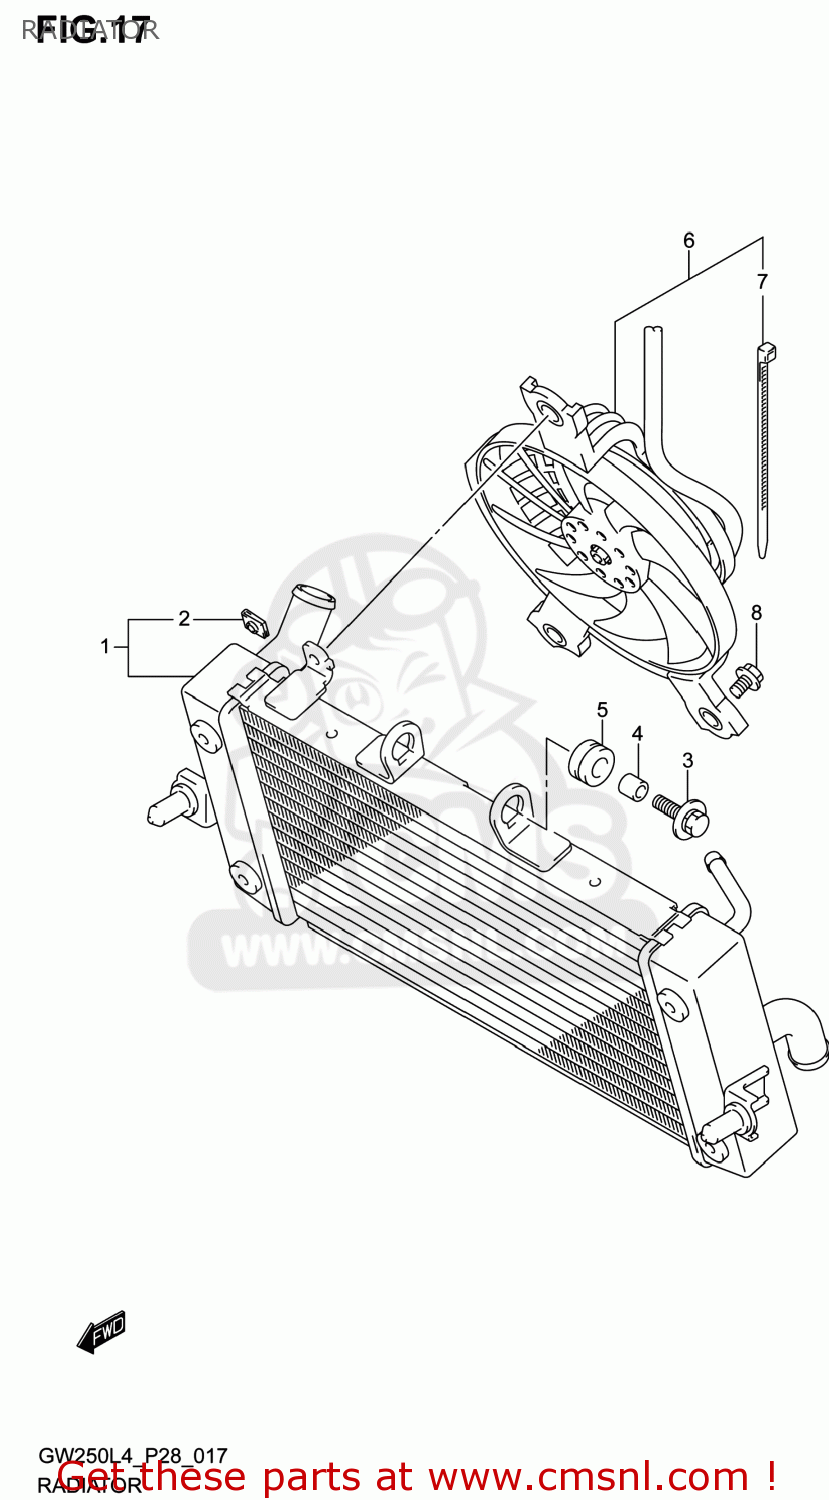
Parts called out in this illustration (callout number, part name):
1	RADIATOR ASSY,WATER
2	NUT
3	BOLT(6X25)
4	SPACER(6.5X10X10)
5	CUSHION
6	FAN ASSY,RADIATOR
7	CLAMP,RR COMBINATION
8	BOLT
